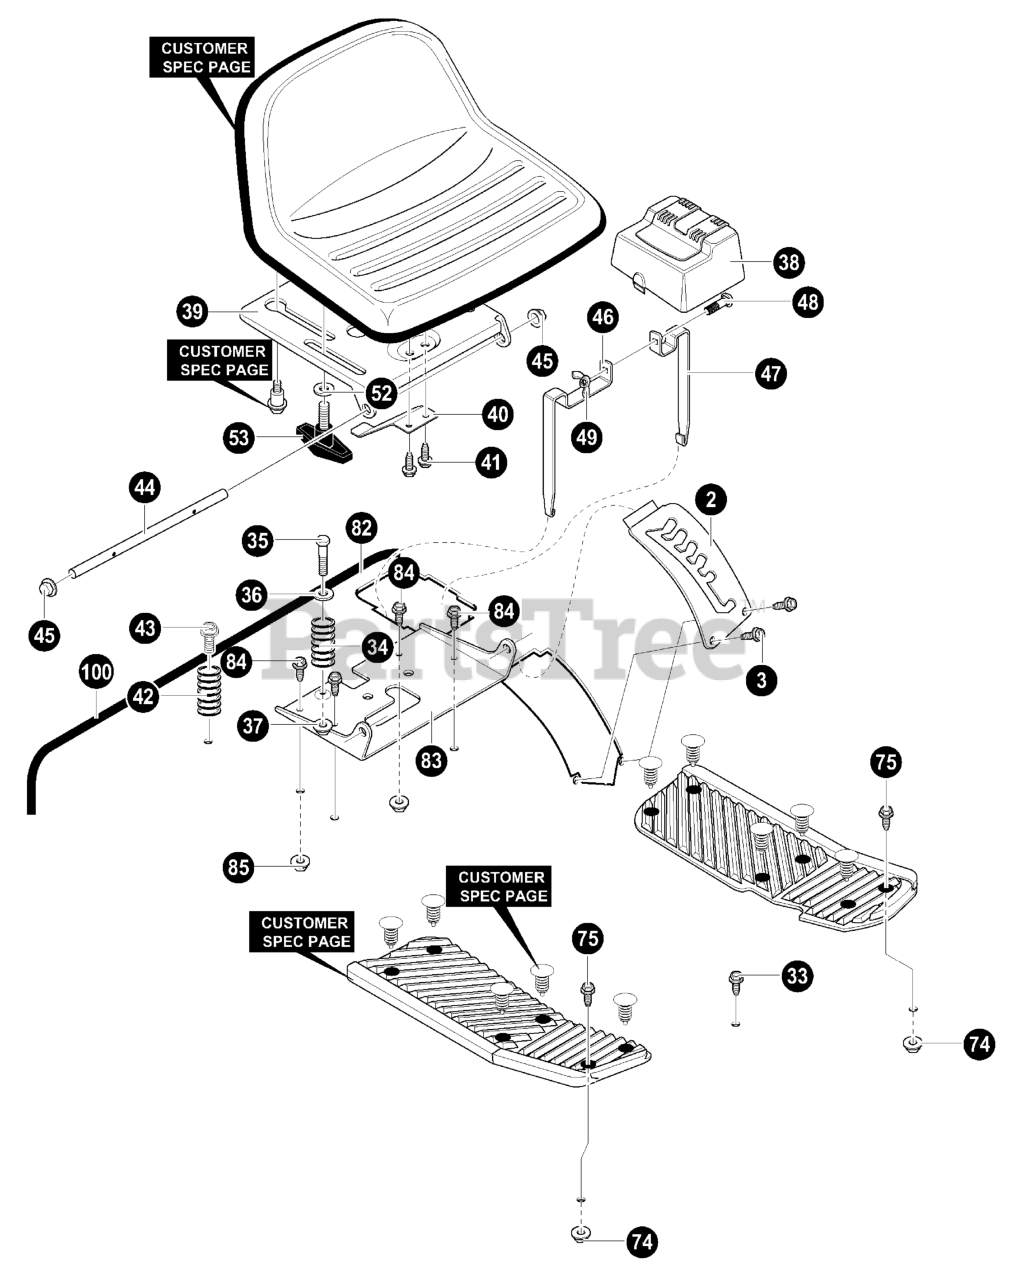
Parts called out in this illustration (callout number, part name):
2	PLATE, LIFT DETENT
3	SCREW, #12X.50 PHPNHTAP
33	SCREW, 5/16-18 x .75 HHWATAP
34	SPRING, COMPRESSION 4.57LGX1.17
35	BOLT, SHOULDER 1/4-20
36	ZINC WASHER CUP
37	NUT, 1/4-20 CENTERLOCK
38	COVER, BATTERY
39	SUPPORT, SEAT
40	SPRING - LEAF
41	SCREW, 1/4-20X.50 WAHHTAP
42	SPRING, COMPRESSION 2.43LG 164X30
43	SCREW, 5/16-18 x 0.75 HHWATAP
44	ZINC HINGE SEAT PIVOT
45	NUT, PUSH CAP .375
46	BATTERY, BRACKET L.H.
47	BATTERY BRACKET R.H.
48	BOLT, 1/4-20X.63 CARR.
49	NUT, WING 1/4-20 14X79
52	WASHER, FLAT .344X.62X.06
53	BOLT, WING 5/16-18X.50
74	NUT, 5/16-18 HEXWDFLLK WHIZ
75	BOLT, 5/16-18X.7A5 CARR.
82	SEAT DECK PEDAL HYDRO
83	BRACKET, PIVOT SEAT
84	SCREW, 5/16-18 x 0.75 HHWATAP
85	NUT, 5/16-18 WDFLLK
